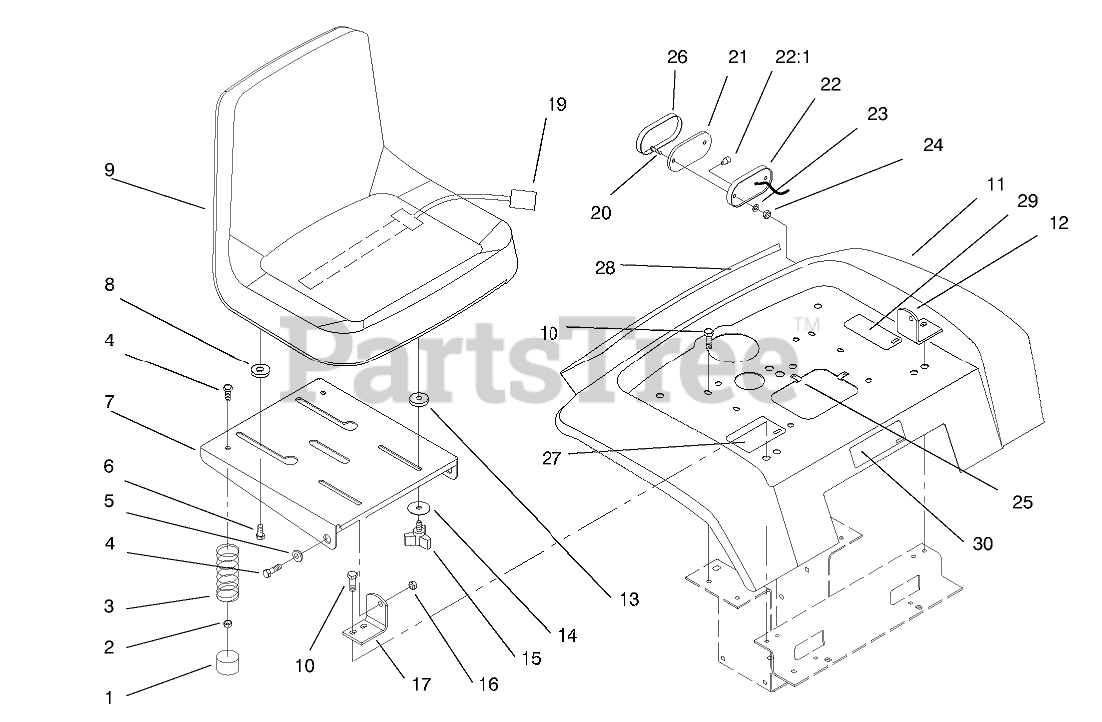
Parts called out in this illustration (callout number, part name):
1	CAP-PROTECTOR
2	NUT-LOCK, NI
3	SPRING-COMPRESSION
4	SCREW-HH
5	BUSHING
6	BOLT-SHOULDER
7	SUPPORT - SEAT (BLACK)
8	SPACER-NYLON
9	SEAT-V-511
10	Bolt
12	BRACKET-PIVOT, LH
13	SPACER-NYLON
14	WASHER
16	NUT-LOCK, NI
17	BRACKET-PIVOT, RH
19	SWITCH-SEAT
20	SCREW-PPH
22	BASE-TAIL LIGHT
23	WASHER-LOCK, INT
24	NUT-LOCK, NI
25	SPEED CLIP
26	LENS-TAIL LIGHT
28	DECAL - REAR FENDER
30	DECAL - USA
